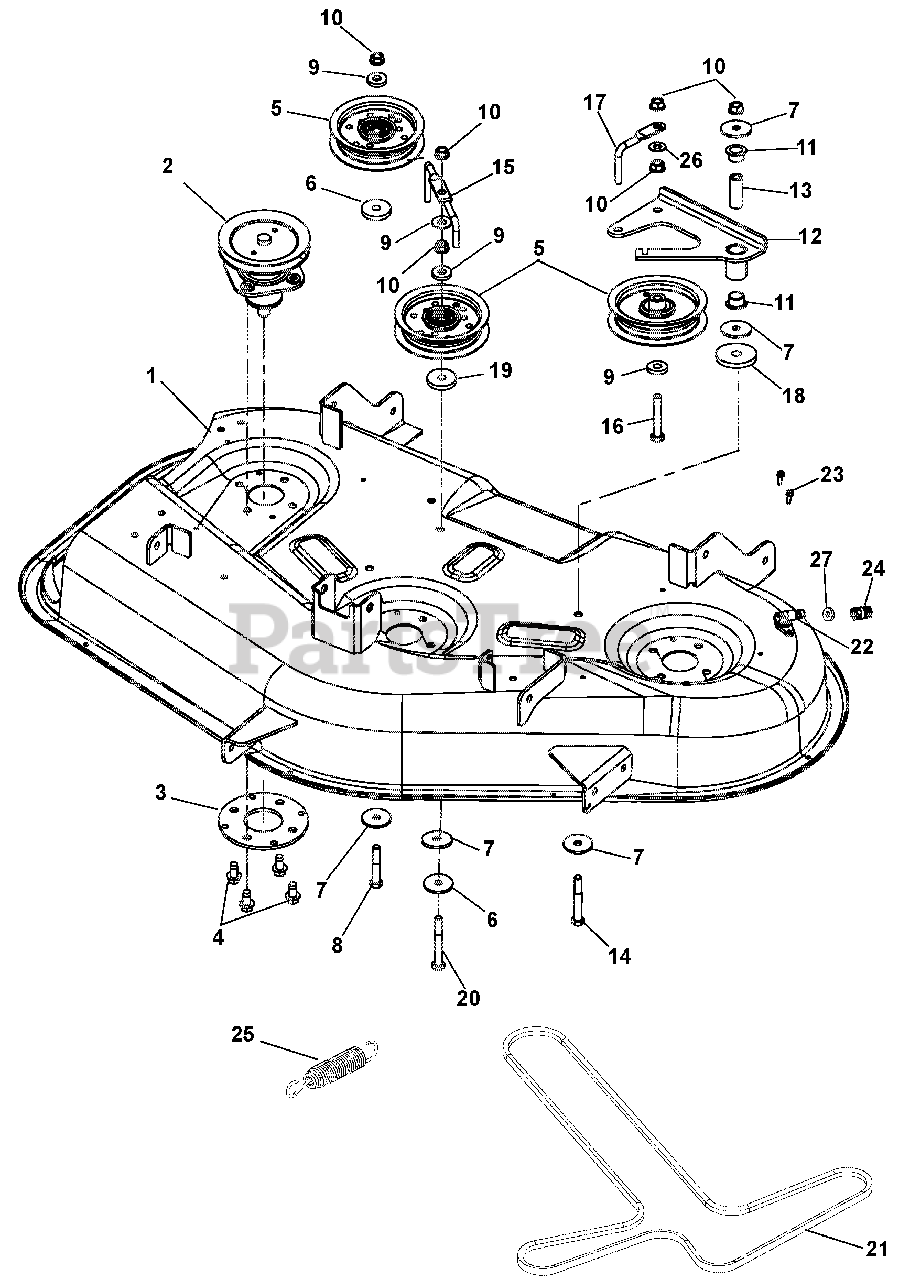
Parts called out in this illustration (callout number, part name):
1	KIT, 42 ARIENS CE DECK W/DECAL
2	KIT, DECK SPINDLE ASM (42)
3	PLATE-REINF, SPINDLE
4	@SCR-TAP .38-16X.75 HWH TR YWZ
5	ASM, IDLER 4"
6	WSHR,FLT STL.406X1.50X.245YWZC
7	WSHR-FL-STL .380X1.50X.125YWZC
8	@BLT-HEX .38-16X2.25 GR5 YWZC
9	WSHR-FL-STL .406X1.00X.188 YWZ
10	@NUT-LK-TOP-FLG .38-16 YWZC
11	BSHG-FLG, .625X.750X.500X1.00
12	IDLER ARM
13	SPACER, .375IDX.625ODX1.66 PM
14	@BLT-HEX .38-16X3.00 GR5 YWZC
15	WIREFORM, BELT FINGER
16	@BLT-HEX .38-16X2.25 GR5 YWZC
17	WIREFORM, BELT FINGER
18	WSHR-FL-STL .469X2.00X.25 YWZC
19	@WSHR-FL-STL.438X1.00X.083 YWZ
20	@BLT-HEX .38-16X2.75 GR5 YWZC
21	V-BELT, 4L-WRAPPED
22	ASSY, WASHOUT PORT W/ O-RING
23	@SCR-TAP .25-20X.62 HWH TR YWZ
24	COUPLING, QUICK DISCONNECT
25	SG-TENS .135X.98X6.0 WLD 62
26	@WSHR-FL-STL.406X.812X.065 YWZ
27	O-RING .362X.103X.568
